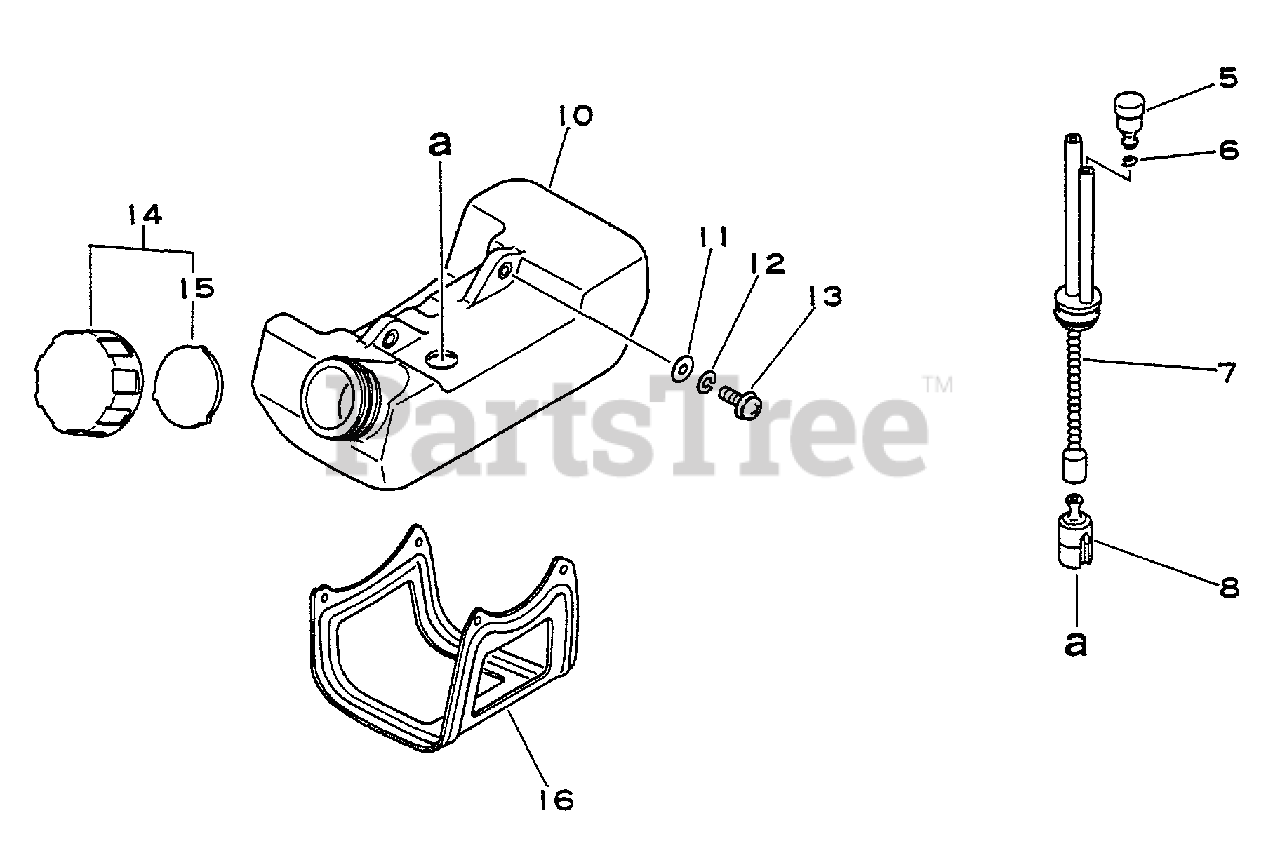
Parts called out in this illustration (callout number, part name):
5	VENT ASSY
7	PIPE, FUEL
8	FILTER, FUEL
10	TANK, FUEL
11	WASHER 5.5×12×0.8
12	WASHER, SPRING 5
13	SCREW 5×16
14	CAP ASSY
15	GASKET
16	GUARD, FUEL TANK
